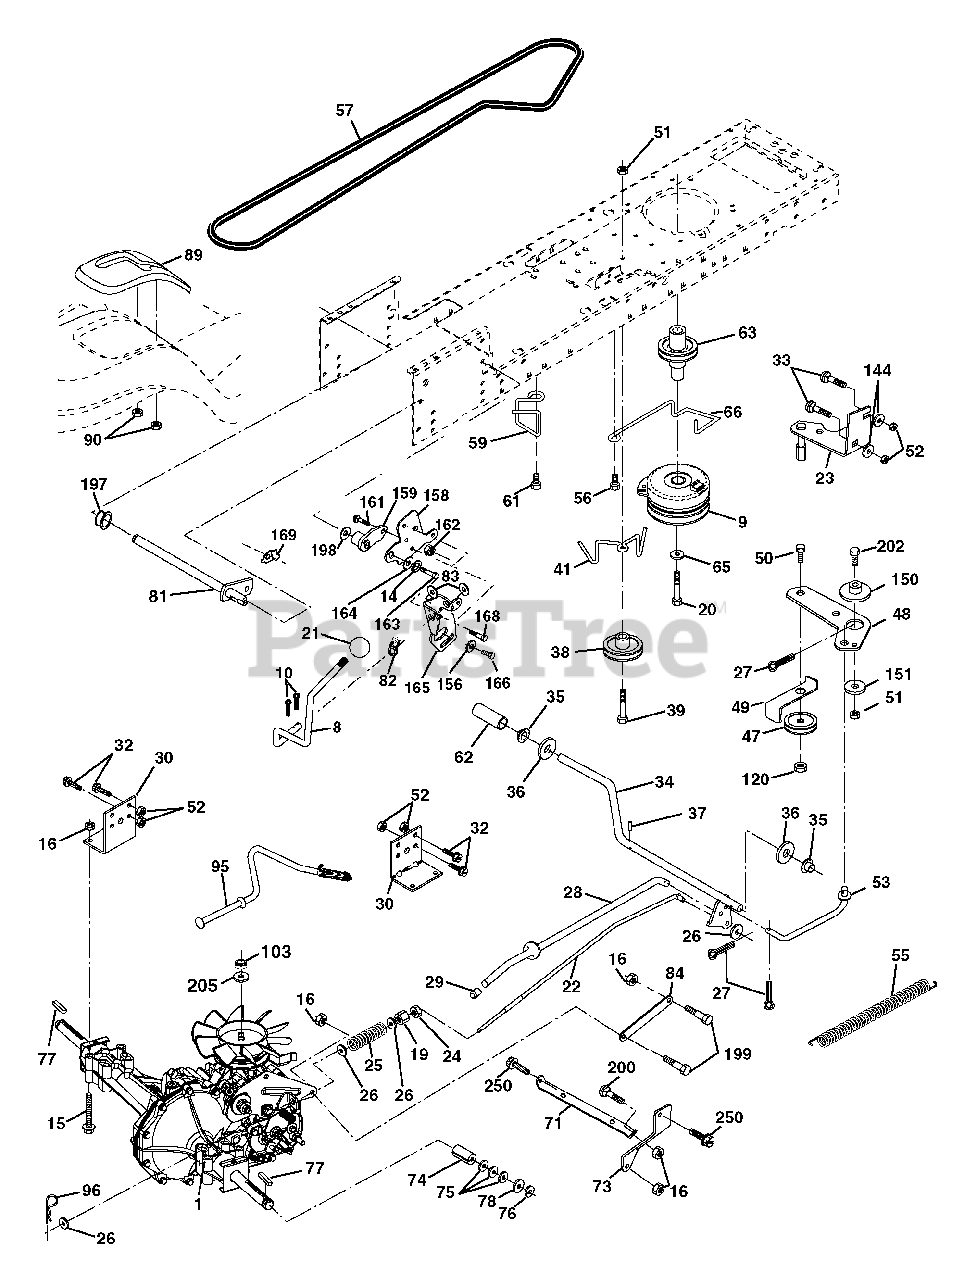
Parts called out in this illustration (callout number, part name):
8	Rod Shift Fender Adjust STLT
9	Clutch Electric
10	Pin Cotter 1/8 x 1 CAD
14	Washer Lock Hvy Helical
15	Bolt Hex 5/16-18 Unc Flghd
16	Nut Lock Hex W/Ins. 5/16-18 Unc P
19	Nut Lock Hex W/Ins 3/8-16 Unc
20	Bolt, Hex 7/16-20 x 4-1/4
21	Knob Deluxe 1/2-13 UNC BLK/BLK
22	Rod, Brake Hydro
23	Bracket Asm Anti-Rot EVX
24	Nut Hex Jam 3/8-16 UNC
25	Spring, Brake Rod
26	Washer
27	Pin Cotter 1/8 x 3/4 CAD.
28	Rod, Parking Brake
29	Cap,Parking Brake
30	Bracket, Transaxle
32	Bolt Hex Hd 5/16-18 Unc x 3/4
33	Bolt Carriage 5/16-18unc x 3/4
34	Shaft, Foot Pedal
35	Bearing, Nylon
37	Pin, Roll
38	Pulley, Composite, Flat
39	Bolt, Fin, Hex 3/8-16 x 3
41	Keeper, Belt Idler
47	Pulley, Idler, V-Groove Plastic
48	Bellcrank Clutch Grnd Drv STL
49	Retainer, Belt Style Spring
50	Bolt 3/8-16 x 1-1/2 Gr. 5
52	Nut Crown Lock 5/16-18
53	Link, Clutch
55	Spring, Return, Clutch
56	Screw 3/8-16 x 1.0
57	V-Belt, Ground Drive
59	Keeper, Center Span
61	Screw 3/8-16 x .875
62	Cover, Pedal
63	Pulley, Engine
65	Washer Lock Hvy HLCL Spr 7/16
66	Keeper Belt Engine
71	Strap Torque Lh Hydro
73	Strap Torque Rh Hydro
74	Spacer, Axle
75	Washer 25/32 x 1-1/4 x 16 Ga.
77	Key, Square
78	Washer 25/32 x 1-5/8 x 16 Ga
81	Shaft Asm Cross Tapered
82	Spring Torsion T/A
83	Washer 17/32 x 3/4 x 16 Ga.
84	Link Transaxle
89	Console, Shift
90	Nut Self Thd 1/4
95	Control Asm. Bypass Hydro
96	Retainer Spring 1 Zinc/Cad
103	Nut Hex Jam Toplock 1/2-20 Unf
120	Nut Lock Flg 3/8-16
144	Washer 11/32 x 5/8 x 16 Ga.
150	Spacer Retainer
151	Washer 13/32 x 2 x 10 Ga.
156	Washer Srrted 5/16ID x 1.125
158	Bracket Shift Mount
159	Hub Tapered Flange Shift Lt
161	Bolt Rdhd Sqnk 1/4-20 x 3/4 Gr 5
162	Nut Crownlock 1/4-20 Unc
163	Bolt Hex Fin 1/4-20 Unc x 1 Gr 5
164	Washer 5/8 x .281 x 10 Ga
165	Bracket Pivot Lever
166	Screw 5/16-18 x 5/8
168	Bolt Shoulder 5/16-18 x .561
169	Plate Fastening STLT/CRD
197	Nyliner Snap 5/8 ID
198	Washer Nyl 7/8 ID x .105 Hyd
199	Bolt Shoulder 5/16-18 Unc
200	Bolt Rdhd Sqnk 5/16-18 Unc x 1
202	Bolt 3/8-16 Unc x 1-3/4 Gr. 5
205	Washer 17/32 x 1 x 16 Ga.
250	Screw 3/8-16 x .75
